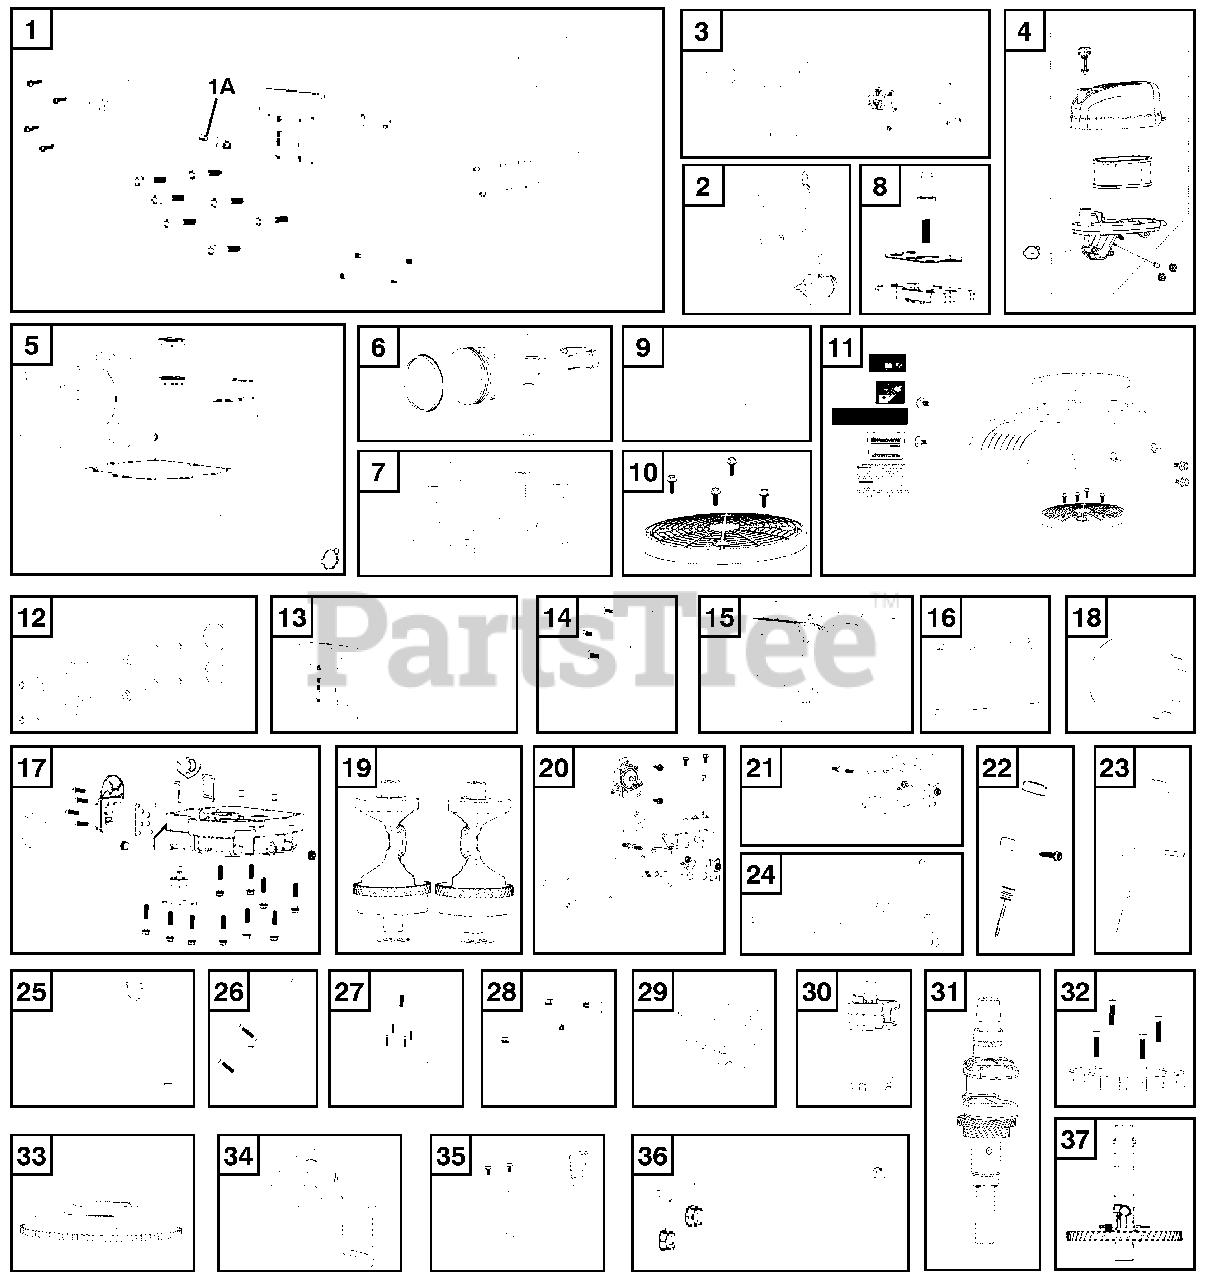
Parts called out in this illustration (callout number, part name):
1	SERVICE KIT CYLINDER HEAD COM
1A	Spark Plug
2	SOLENOID KIT
3	Carburetor Kit
3	SERVICE KIT CARBURETOR,KIT. TR
4	SERVICE KIT KIT.AIR.CLEANER/60
5	SERVICE KIT GASKET.SEAL KIT
6	SERVICE KIT PISTON AND RING SE
7	SERVICE KIT FAN COOLING AND FA
8	SERVICE KIT REEED VALVE KIT
9	SERVICE KIT VALVE BREATHER KIT
10	SERVICE KIT KIT.FAN.COOLING.CO
11	COVER COVER,STARTER./608
12	SERVICE KIT KIT.VALVE (KIT 12)
13	Cylinder Head Kit Kit
14	SERVICE KIT KIT.AIR.DEFLECTOR
15	SERVICE KIT KIT.CRANKCASE.BODY
16	AIR FILTER AIR FILTER.608
17	SERVICE KIT KIT.CRANKCASE.COVE
18	Oil Filter
19	SERVICE KIT KIT.CRANKSHAFT.BAL
20	SERVICE KIT KIT.THROTTLE.LEVER
21	SERVICE KIT KIT.THROTTL.LEVER
22	SERVICE KIT KIT.FILLER.TUBE. (
23	SERVICE KIT FILL TUBE KIT W/FU
24	SERVICE KIT KIT.SPEED.REGULATI
25	SERVICE KIT KIT.FILLER.TUBE. (
26	SERVICE KIT KIT.VOLTAGE.RECTIF
27	SERVICE KIT KIT.SIDE.PLATE (KI
28	SERVICE KIT KIT.BOLT. (KIT 30)
29	SERVICE KIT KIT.GOVENOR.GEAR.
30	SERVICE KIT KIT.STARTER.MOTOR
31	SERVICE KIT KIT.CRANK.SHAFT
32	SERVICE KIT KIT.CHARGING.ARMAT
33	SERVICE KIT KIT.FLYWHEEL
34	SERVICE KIT KIT.OIL.STRAIN
35	MODULE KIT.FUEL.SYSTEM
36	SERVICE KIT KIT.BREATHER.TUBE
37	CAMSHAFT KIT
